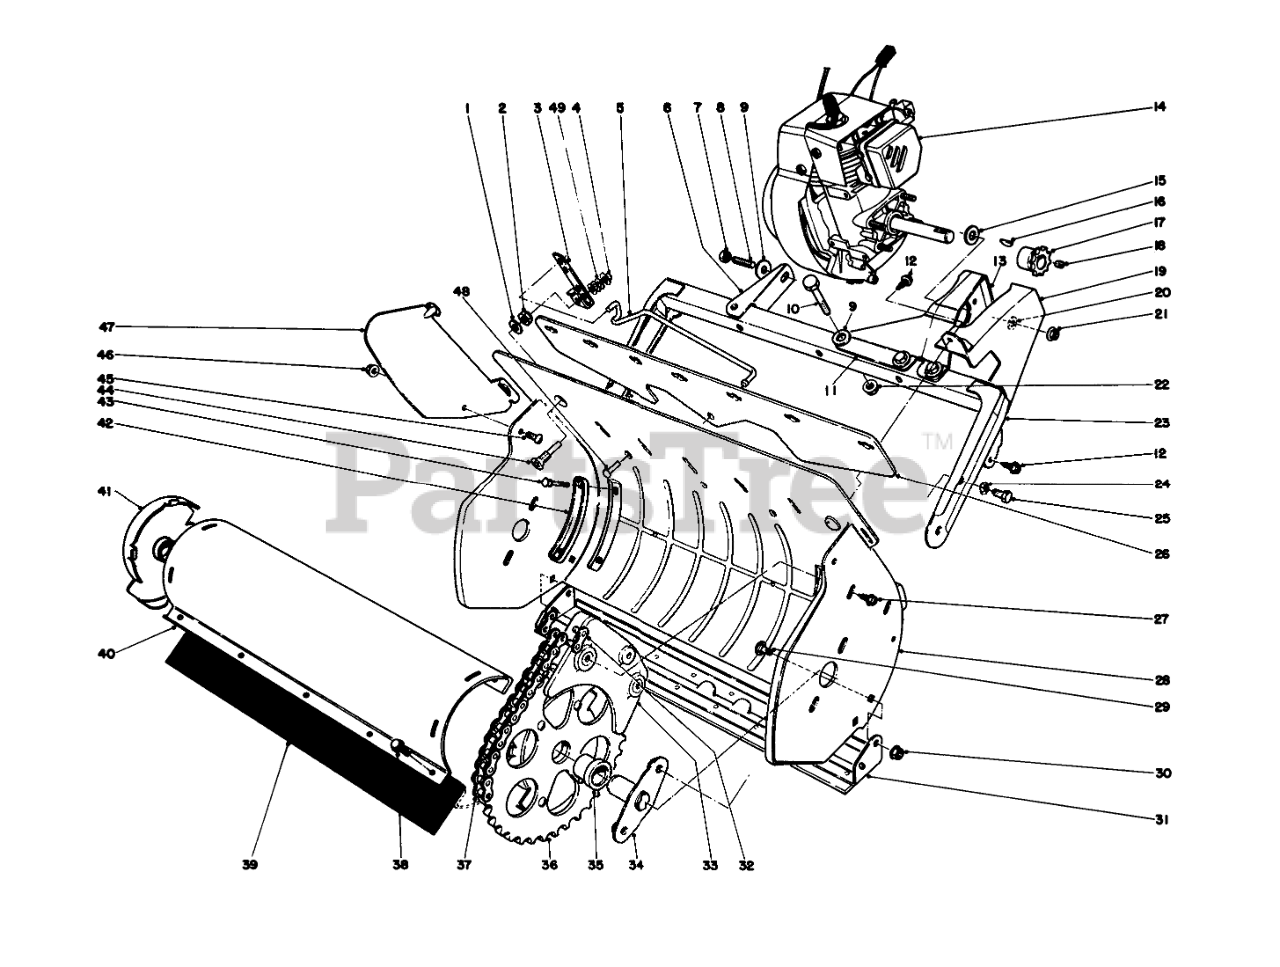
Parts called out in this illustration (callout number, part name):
1	WASHER-FLAT
2	NUT-LOCK, NI
3	Bracket Vane Adjustment
4	NUT-SPEED
5	Linkage Vane Adj.
6	Frame Bracket
7	NUT-LOCK, CONE
9	WASHER-FLAT
10	SCREW-HH
11	Engine Bracket Internal
12	SCREW-HWHTF
13	Engine Bracket External
14	Engine
15	WASHER-PLAIN
16	KEY-WOODRUFF
17	SPROCKET
18	SCREW-HSH
19	Chain Guard
20	Lockwasher
21	NUT-HF
22	NUT-LOCK, HHF
23	Frame
24	Washer
25	Screw
26	VANE MOUNT
27	Screw
28	Housing
29	SCREW-CARR
30	NUT-KEPS
31	Skid
32	LINK-CONNECTING, NO. 35
33	Stripper
34	ROTOR SHAFT ASM
35	ROTOR BUSHING
36	End Cap Assembly L.H. (Incl. Ref. #35)
37	ROLLER CHAIN
38	SCREW-TAP
39	ROTOR BLADE
40	ROTOR SHELL
41	End Cap Assembly R.H. (Incl. Ref. #35)
42	Handle Plate
43	SCREW-CARR
44	Screw
45	SCREW-PTH
46	NUT-LOCK, FLANGE
47	Vane
48	Pop Pivot
49	WASHER-FLAT
